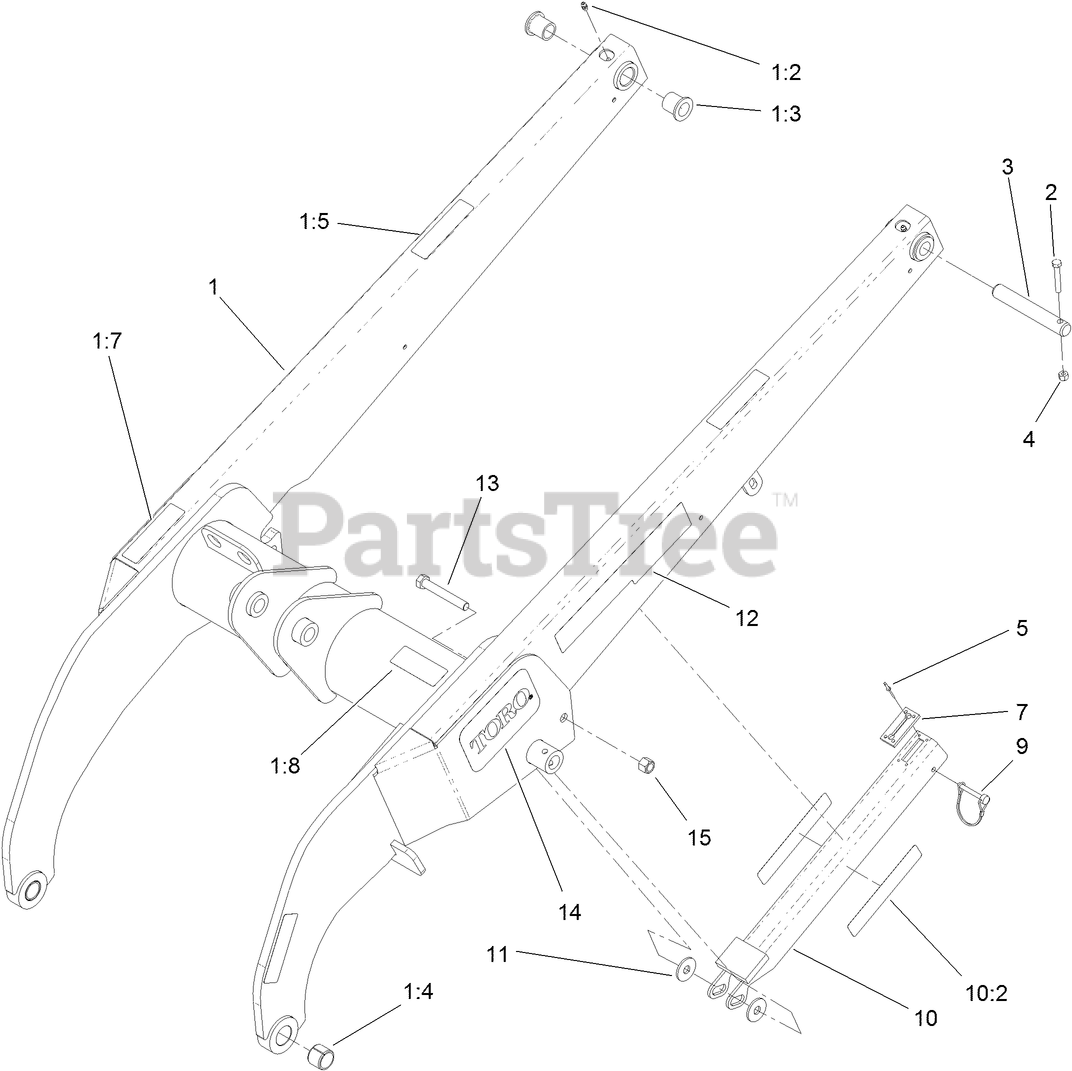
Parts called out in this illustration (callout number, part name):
1	LOADER ARM ASM
1:2	FITTING-GREASE
1:3	BUSHING
1:4	BUSHING-TENSION
1:5	DECAL-WARNING, PINCH
1:7	DECAL-CAUTION
1:8	DECAL-NO RIDER
2	SCREW-HH
3	PIN-LOCKING
4	NUT-LOCK, NI
5	RIVET
7	STOP-RUBBER
9	PIN-LOCKING
10	LOCKING ARM ASM
10:2	DECAL-DANGER
11	WASHER-RUBBER
13	SCREW-HH
15	NUT-LOCK, NI
